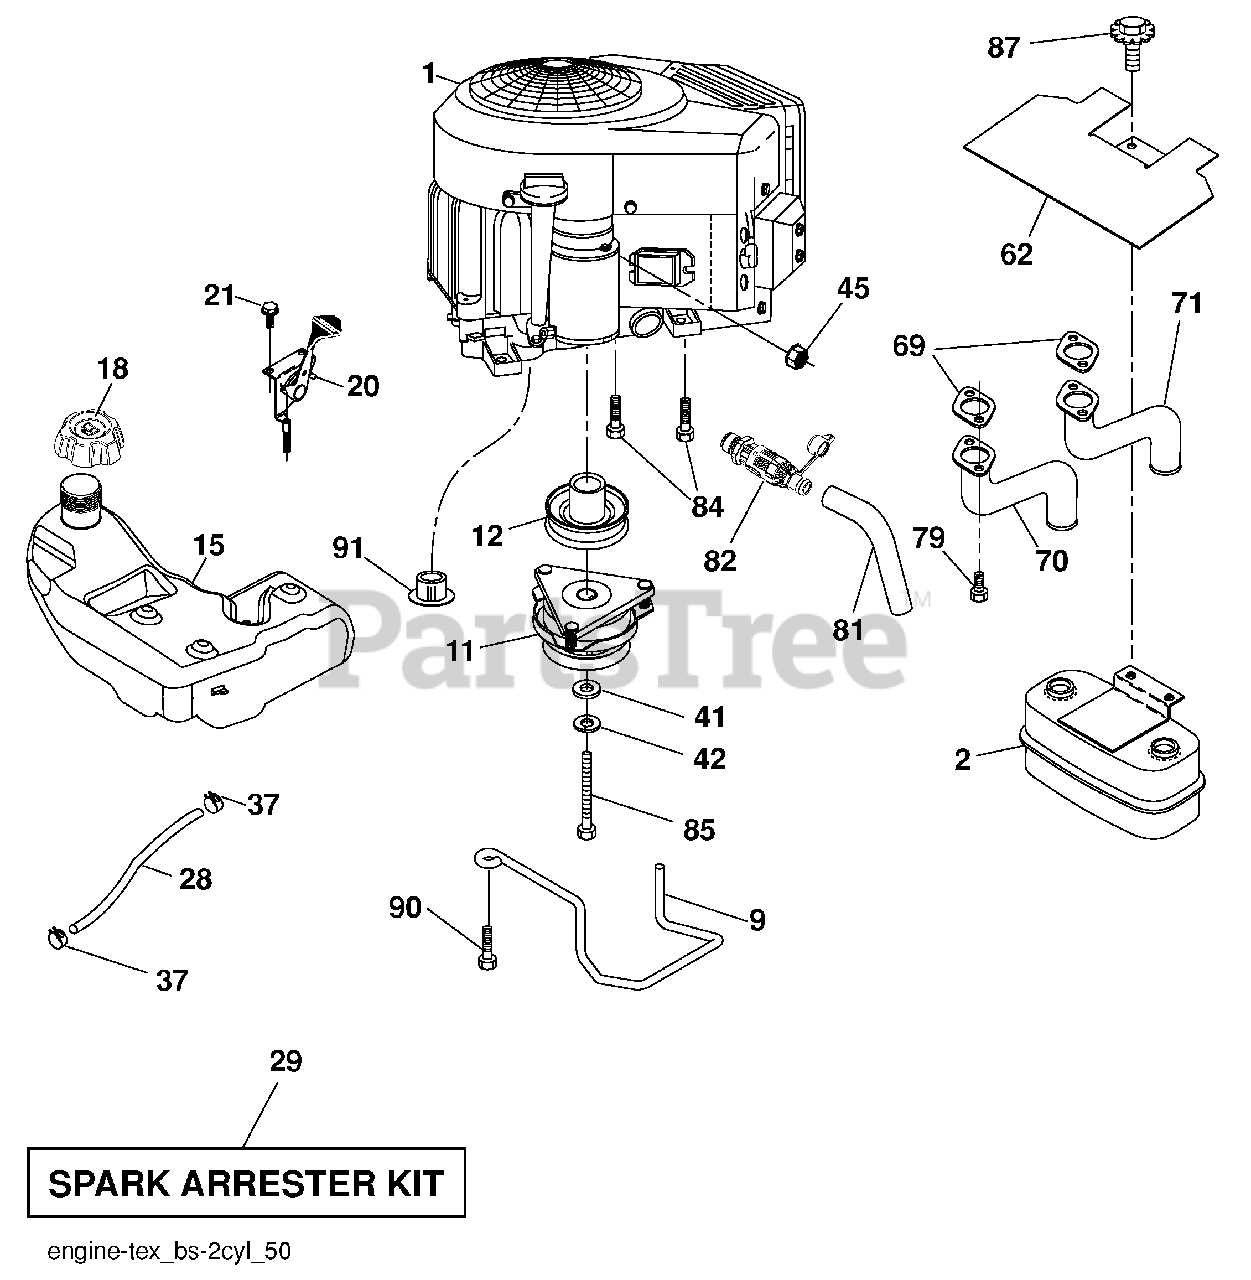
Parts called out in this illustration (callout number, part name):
1	Engine Briggs Model No. 445577-1187-B1
2	Muffler
9	Keeper Belt Engine
11	Clutch Electric
12	Pulley Engine
15	Tank Fuel
20	Control Throttle
21	Screw #10 x 0.750 BOS Thread
29	Spark Arrester Kit
37	Clamp Hose
41	Washer 1-1/2 OD x 15/32 ID x .250
42	Washer Lock 7/16
45	Nut Keps Hex 1/4-20 unc
62	Shield Heat Muffler
69	Gasket
70	Tube Exhaust LH
71	Tube Exhaust RH
79	Screw Socket Head 5/16-18 x 1
81	Tube Drain Oil Easy
82	Valve Oil Drain
84	Screw 3/8-16 x 1-1/4
85	Bolt Hex 7/16-20 x 4 Gr. 5
87	Bolt 5/16-18 unc x 1 w/Sems
90	Screw 3/8-16 x 1
91	Bushing
